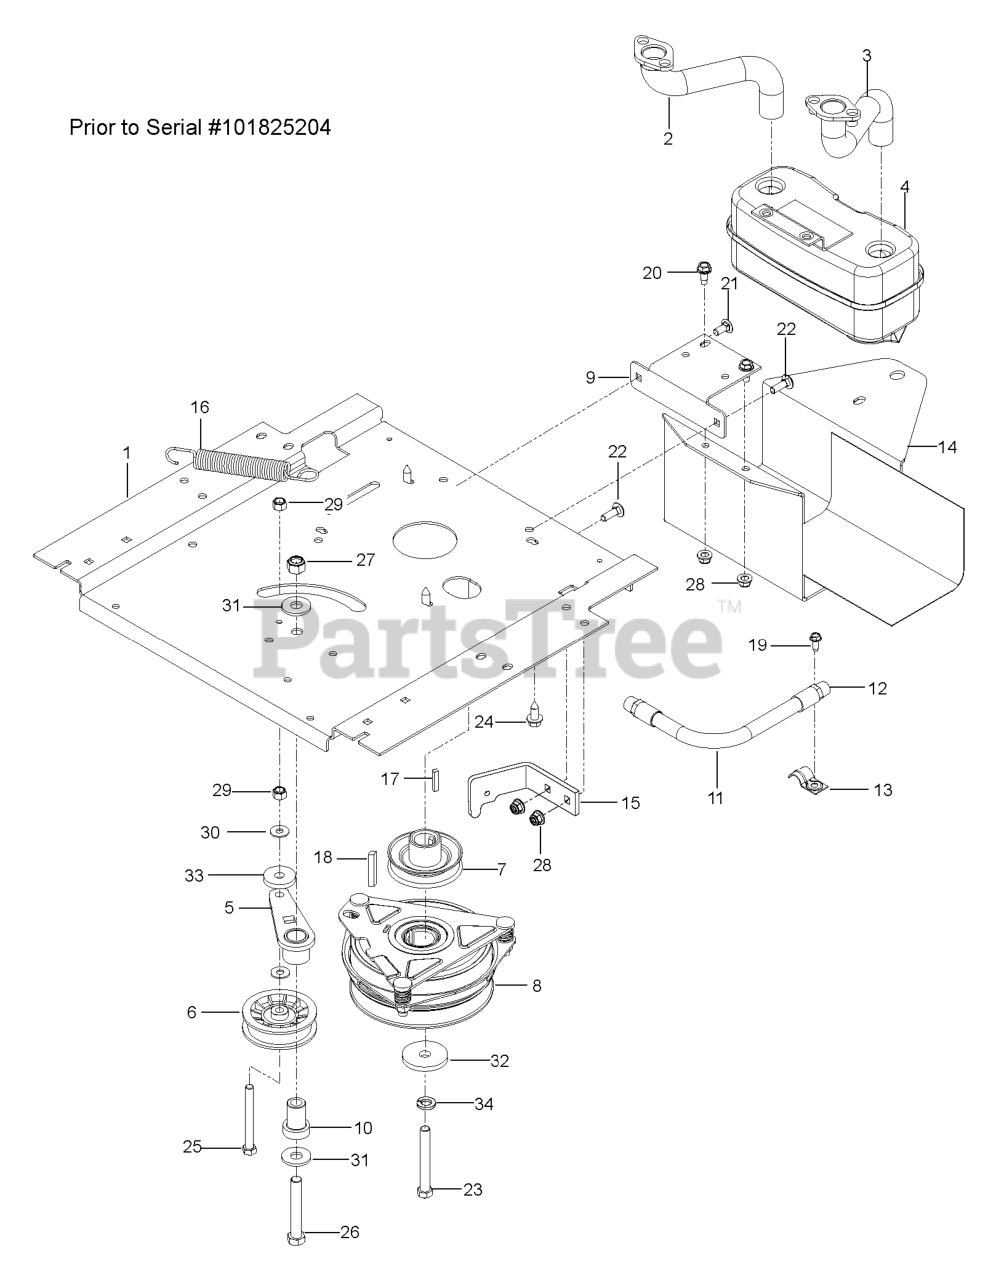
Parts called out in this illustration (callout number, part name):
1	PLATE ENGINE, BLACK
2	RP.PIPE-EXHAUST LH
3	RP.PIPE-EXHAUST RH
4	MUFFLER ASM TWIN
5	RP.IDLER ARM WELDMENT
6	PULLEY, IDLER RAKE & ZTR
7	PULLEY, C'SHAFT, 3.57 OP
8	CLUTCH, 150 FT/LBS
9	BRACKET, MUFFLER, BLACK
10	PIVOT, IDLER
11	OIL DRAIN HOSE
14	GUARD, MUFFLER, BLACK
15	STOP, CLUTCH OGURA BLK
16	SPRING, DECK DRIVE
17	KEY, 1/4 SQ X 1 1/4
18	KEY 1/4 SQ X 2
19	SCREW 1/4 X 5/8
20	BOLT 5/16-18 X 3/4
21	BOLT 5/16C X 3/4" CARRIAGE
22	RHSNB 5/16C X 1
23	HCS 7/16-20 X 2 G8 ZN
24	HHFS 3/8-16 X 1.0 THD FORMING
25	HCS 3/8-16X3 1/2 GR5
26	HCS 1/2C X 2 3/4
27	NUT 1/2-13 HEX NYLOC ZD
28	5/16-18 NYLOC FLANGE NUT
29	NUT 3/8-16 NYLOC
30	WASHER 5/16 FLAT
31	WASH USS FLAT 1/2
32	SPINDLE WASHER
33	HEAVY WASHER
34	WASHER 7/16 LOCK
